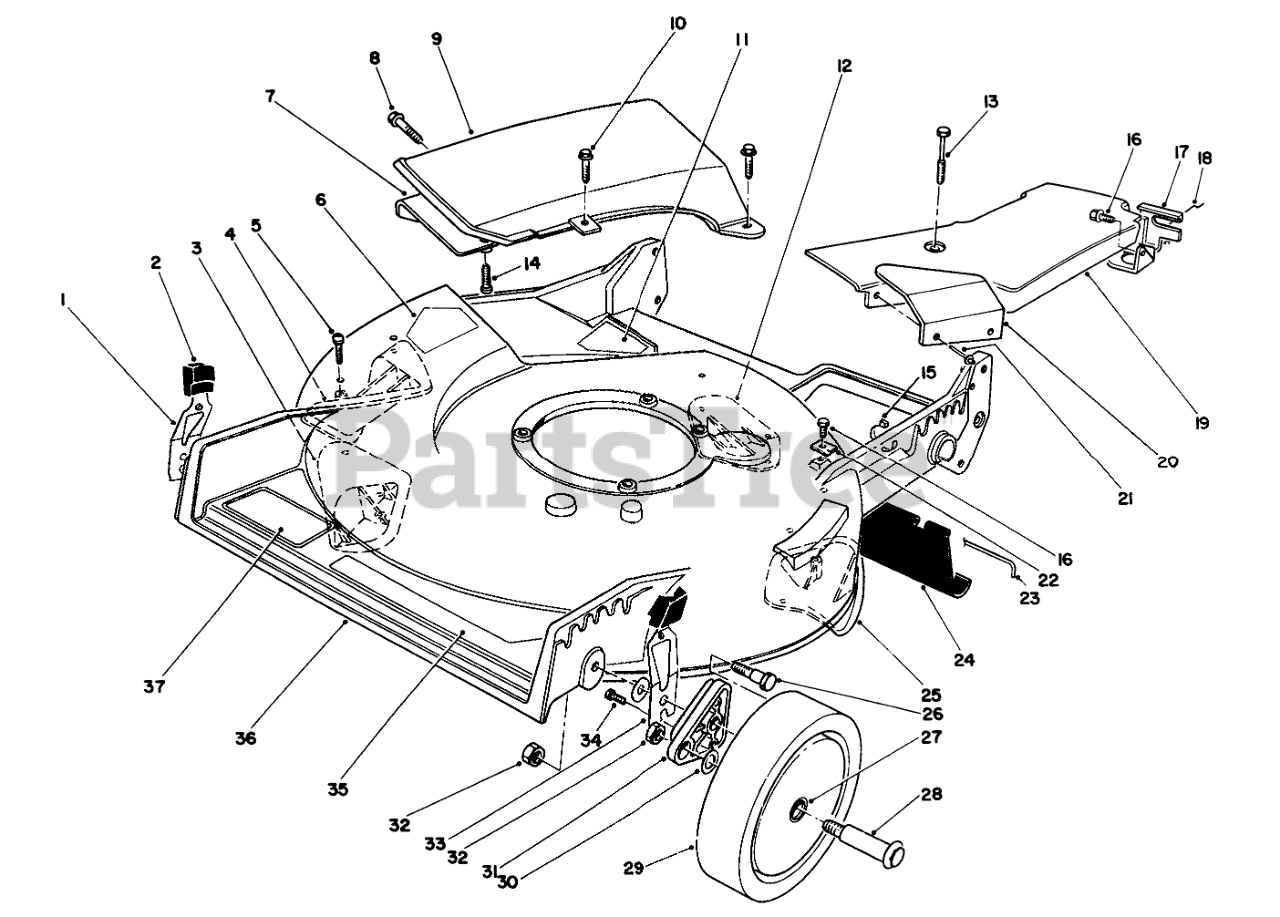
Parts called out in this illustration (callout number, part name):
1	RH SPRING ARM ASSEMBLY
2	KNOB-ARM
3	KICKER
4	KICKER
5	SCREW-PPH
6	DECAL-DANGER
7	Deflector-Recycler
8	SCREW AND WASHER ASM
9	Cover Assembly (Incl. Ref. #7 & 14)
10	SCREW-HWH
11	DECAL - DANGER
12	KICKER
13	SCREW-HHFTF
15	TIE-CABLE
16	SCREW-HWHTF
17	Bracket-Adj. Trac
18	RETAINER-CABLE
19	Belt Cover Assembly (Incl. Ref. #20 & 21)
20	HEAT SHIELD
21	RIVET-HEAD, FLAT
22	CLAMP-CABLE
23	ROD-SHIELD
24	SHIELD-TRAILING
25	KICKER
26	SCREW-SHOULDER
27	BUSHING
28	WHEEL BOLT
29	Wheel & Tire Assembly (Incl. Ref. #27)
30	WASHER
31	ARM-PIVOT, FRONT
32	Nut
33	LH SPRING ARM ASSEMBLY
34	SCREW-HWH
35	DECAL - DECK
36	Housing Assembly (Incl. Ref. #3-6, 12, & 25)
37	DECAL
